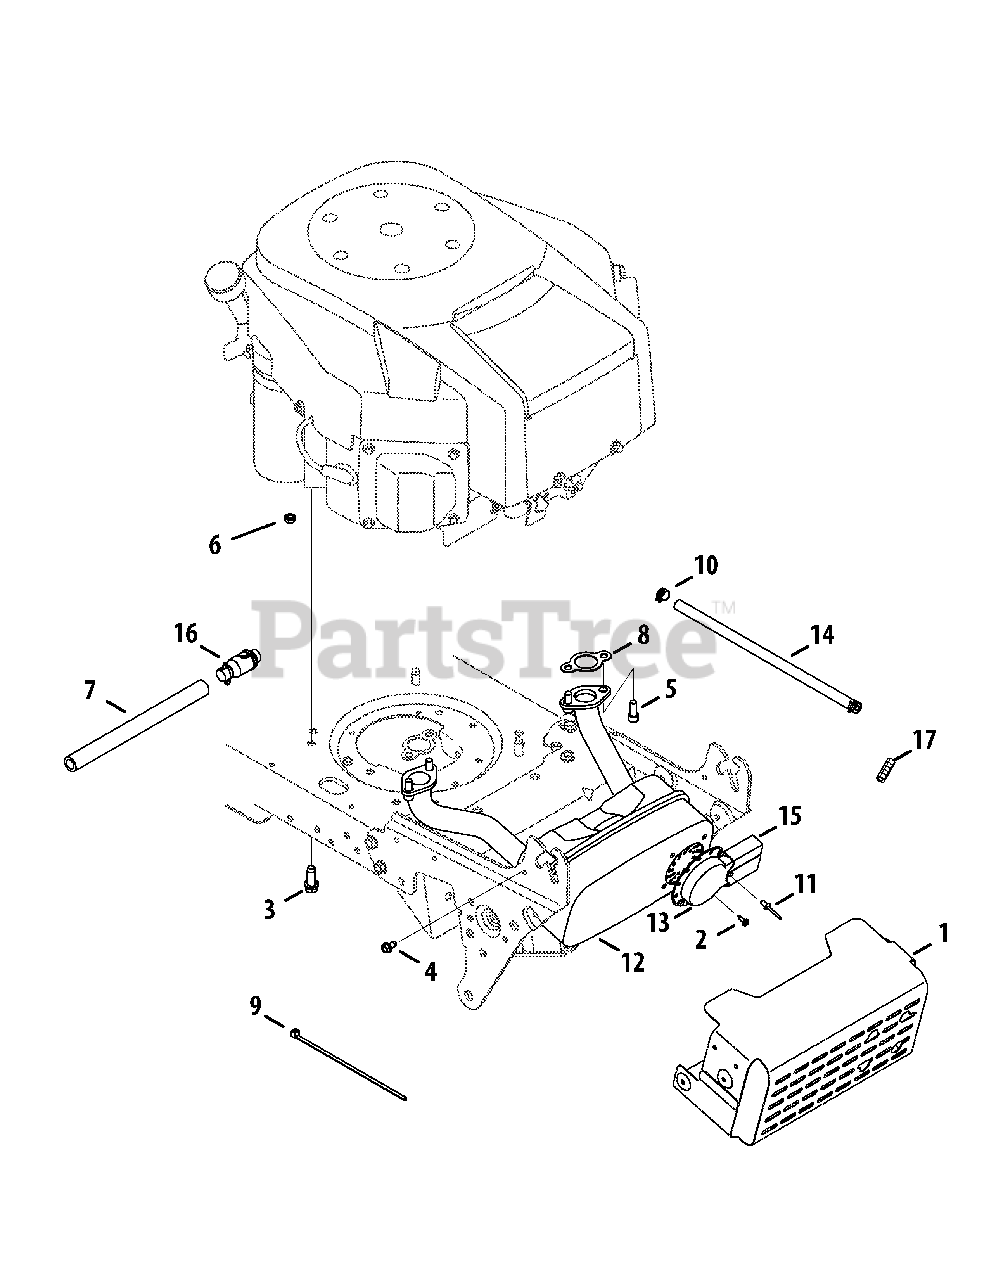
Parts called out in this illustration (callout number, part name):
1	Shield Ass’y, Muffler
2	Screw, Ab, #8-18, 0.500,
3	Screw, Self-tapping, 3/8-16, 1.000,
4	Screw, Self-tapping, 1/4-20, 0.500,
5	Screw, Socket Head, 5/16-18, .750
6	Nut, Sems, 1/4-20
7	Hose, Extension, Oil Drain
8	Gasket, Exhaust
9	Cable, Tie, 3/16 x .05 x 7.4
10	Clamp, Hose, .490 Dia.
11	Rivet, Pop, .188 Dia x .300
12	Muffler, Kohler Twin
13	Deflector, Muffler
14	Hose, Fuel, Low Permeation, 1/4
15	Deflector, Muffler, Long
